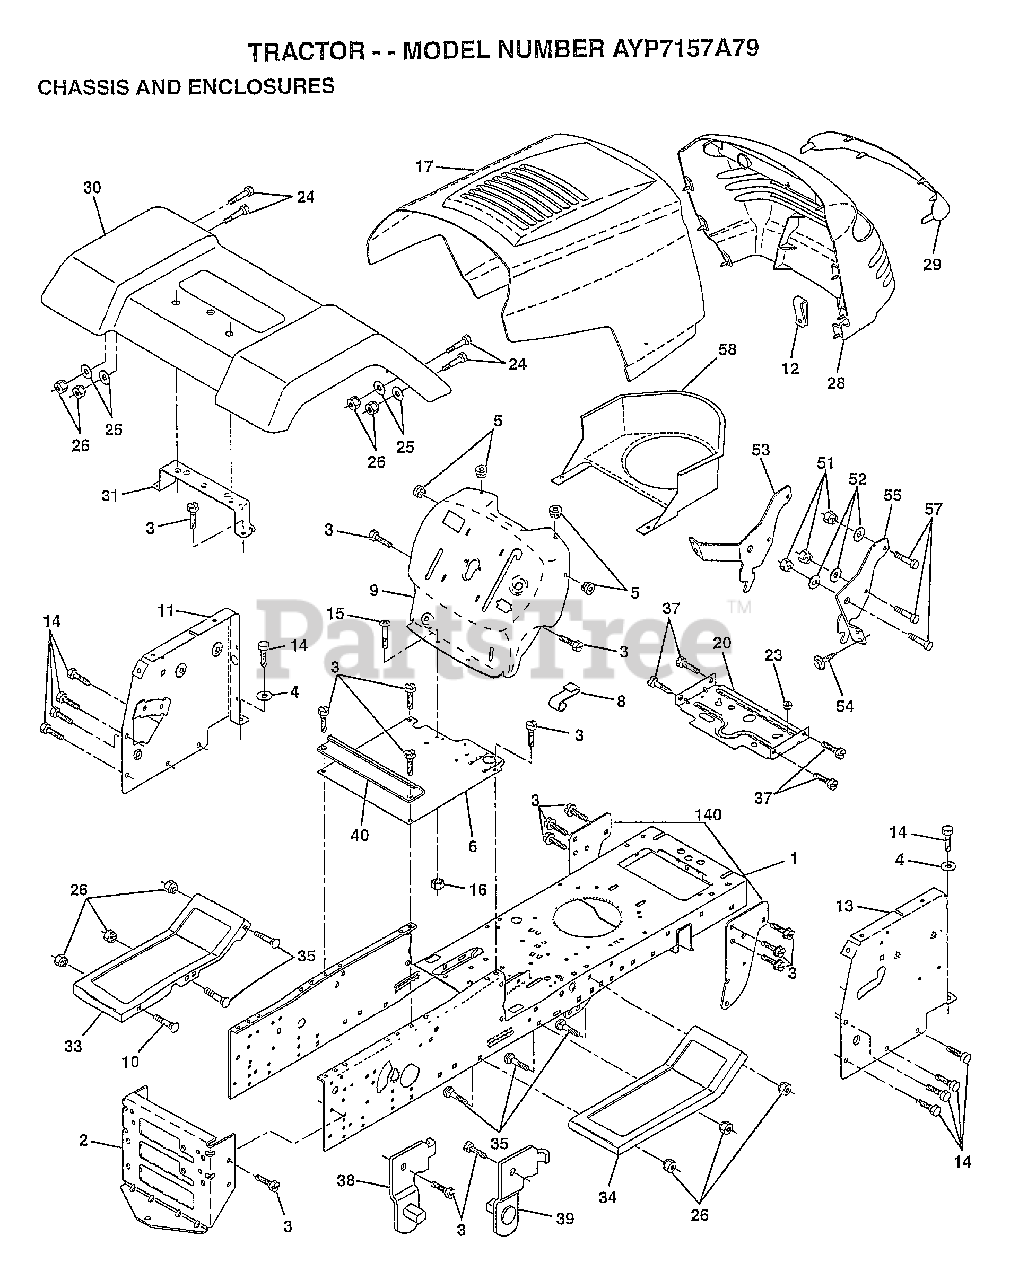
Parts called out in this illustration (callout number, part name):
1	CHASSIS ASM
3	SCREW
4	WASHER
5	BUMPER-HOOD/DASH
6	SADDLE
8	"CLIP,INSULATOR"
9	DASH SILKSCREEN
11	"PANEL-DASH,LH"
12	CLIP.TINNERMAN
13	"PANEL-DASH,RH"
14	SCREW LT
15	SCREW
17	HOOD.STL.PRV.LB
20	"PLATE-MTG,BATT/FU"
24	BOLT
25	WASHER
26	NUT
28	GRILL
29	LENS.EURO.W/DECAL
31	BRACKET SUPT FEND
33	FOOTREST.LT.LT/GT
34	FOOTREST.RH.LT/GT
35	BOLT
37	SCREW LT
38	BRACKET ASM LH
39	BRACKET ASM RH
40	SPACER FENDER LT
51	NUT
52	WASHER
53	BRACKET.GRILLE.LH
55	BRACKET.GRILLE.RH
58	AIR DUCT
140	BRKT SUSPENSION
